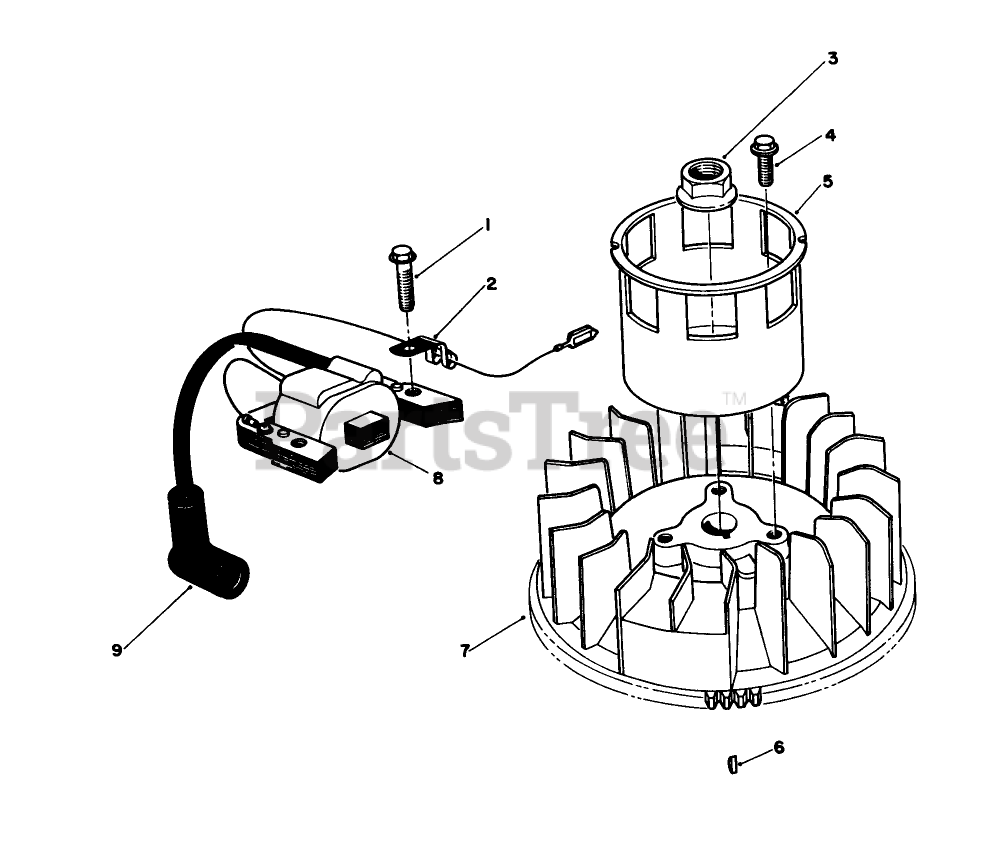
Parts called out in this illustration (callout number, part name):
2	CLAMP
7	FLYWHEEL
8	COIL
9	COVER
